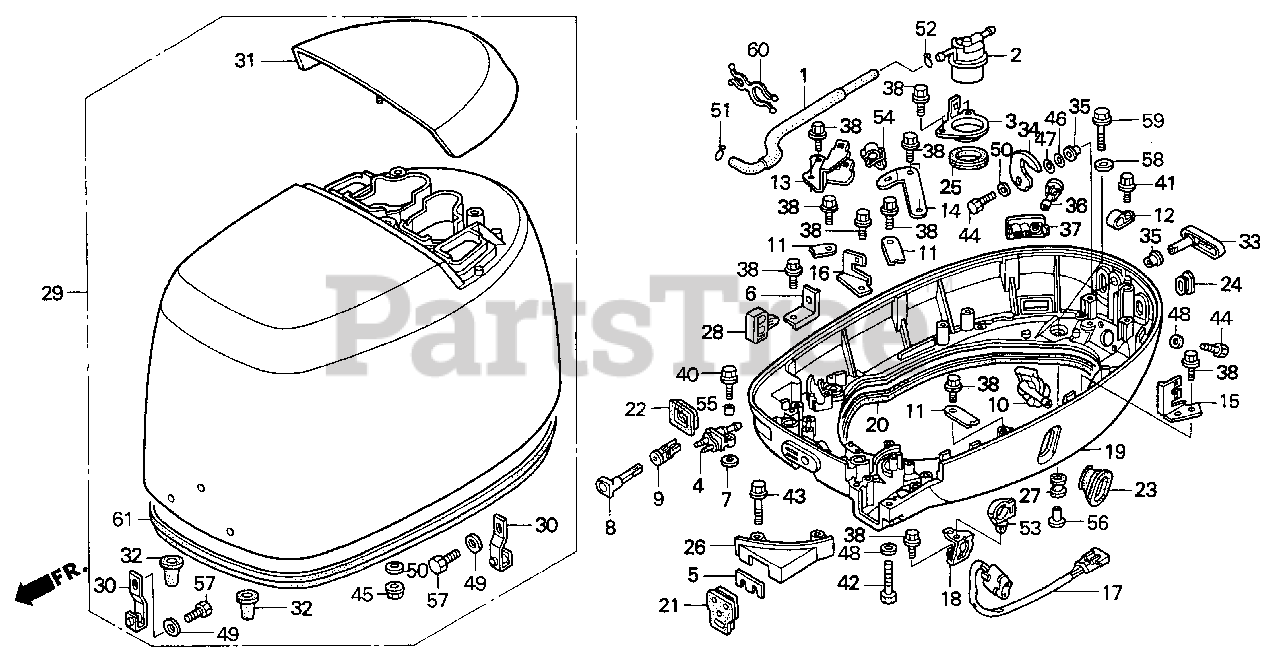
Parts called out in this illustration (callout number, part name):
1	TUBE, FUEL
2	FILTER, FUEL (TOYO ROKI)
3	STAY, FUEL STRAINER
4	CONNECTOR SET, FUEL
4	CONNECTOR ASSY. B, FUEL
5	PLATE, REMOTE CONTROL CABLE
6	HOLDER, THROTTLE CABLE
7	WASHER, PIVOT
8	KNOB, CHOKE
9	GUIDE, CHOKE KNOB
10	JOINT, WATER INLET
11	PLATE, SHIFT SHAFT
12	CLAMP, IGNITION WIRE
13	BRACKET, CONNECTOR
14	BRACKET, CLIP A
15	BRACKET, CLIP B
16	BRACKET, HARNESS CLIP
17	SWITCH ASSY., POWER TRIM-TILT
18	STAY, POWER TILT SWITCH
19	CASE, ENGINE (LOWER) (000) *NH282MU* (OYSTER SILVER METALLIC-U)
20	SEAL, CASE (LOWER)
21	GROMMET, CASE (LOWER) (A)
22	GROMMET, CASE (LOWER) (B)
23	GROMMET, CASE (LOWER) (G)
24	GROMMET, CASE (LOWER)
25	GROMMET, FUEL STRAINER
26	CASE, SEPARATE *NH282MU* (OYSTER SILVER METALLIC-U)
27	RUBBER, FR. CARRIER CUSHION
28	CLIP, RETURN PIPE (6MM)
29	COVER ASSY., ENGINE *NH282MU* (OYSTER SILVER METALLIC-U)
30	HOOK, ENGINE COVER
31	HANDLE, TILT *NH282MU* (OYSTER SILVER METALLIC-U)
32	DAMPER, HOOK
33	LEVER, COVER LOCK *NH282MU* (OYSTER SILVER METALLIC-U)
34	HOOK, COVER LOCK
35	BUSH, COVER LOCK
36	GROMMET, WATER CHECK
37	GROMMET, WATER CHECK
38	BOLT, FLANGE (6X12)
40	BOLT, FLANGE (6X20)
41	BOLT, FLANGE (5X10)
42	BOLT, HEX. (6X35)
43	BOLT, FLANGE (6X28)
44	BOLT, HEX. (6X16)
45	NUT, U (6MM)
46	WASHER (14MM)
47	WASHER, WAVE (14MM)
48	WASHER, PLAIN (6MM)
49	WASHER, PLAIN (8MM)
50	WASHER (6MM)
51	CLIP, TUBE (B10)
52	CLIP, TUBE (B12)
53	CLAMP, HARNESS
54	CLIP, CABLE
55	COLLAR, DISTANCE (6MM)
56	COLLAR (8.3X14.5)
57	BOLT, HEX. (8X16)
58	WASHER, FLAT (8MM)
59	BOLT, FLANGE (8X35)
60	CLIP, PURSE LOCK
61	SEAL, ENGINE COVER
